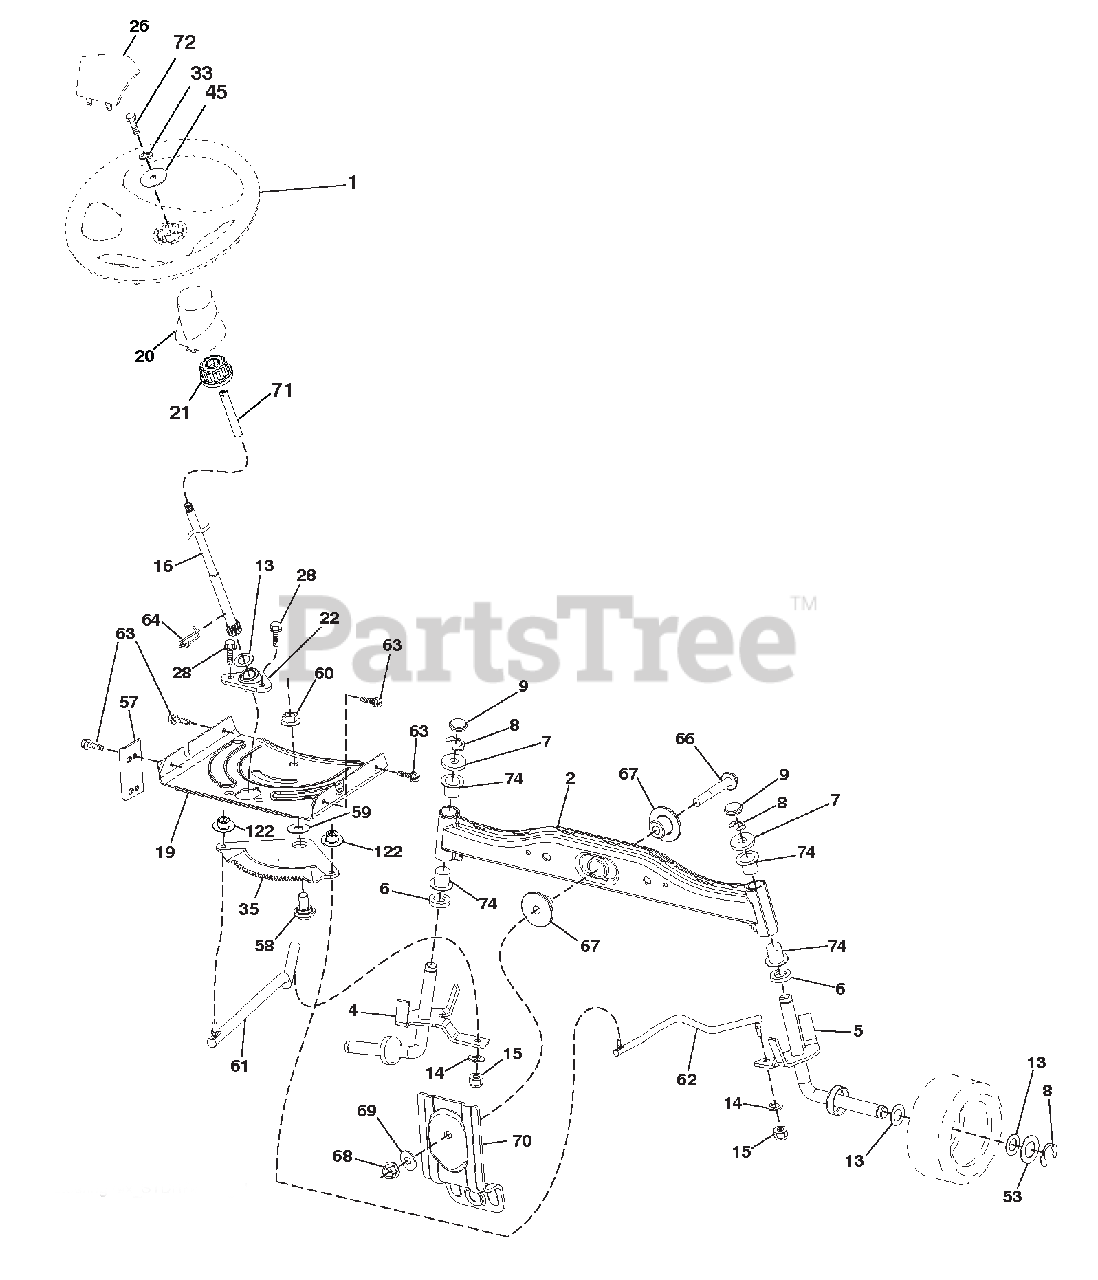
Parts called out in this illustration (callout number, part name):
1	Wheel Steering
2	AXLE ASM.WELDED
4	SPINDLE.ASM.LH
5	SPINDLE.ASM.RH
6	WAHSER THRUST .75 X 1.230
7	WASHER.25/32 X 1-5/8 X 16GA.
8	RING.KLIP.#T5304-75
9	CAP.SPINDLE.FR.TOP.BLK.
13	WASHER.25/32 X 1 1/4 X 16 GA.
14	Washer, Lock 3/8
15	NUT.CROWNLOCK.3/8-24
16	SHAFT.STEER.3/4 TEX.NON-PLATED
19	PLATE.STEER.DDL.NLT/NGT
20	BOOT STEERING
21	ADAPTER.WHEEL.STRG..760
22	STEERING SUPT.LOWER
26	Cap Wheel Steer
28	SCREW.HEXWSH THDR3/8-16X3/4.BL
33	Washer, Lock 5/16
35	GEAR SECTOR.PLATE.DDL.NLT/NGT
45	WASHER.11/32ID X2 3/8OD X 12GA
53	WASHER.HARDEN..793 X 1.637X060
57	BRACKET.UPSTOP.TEX
58	BOLT.SHOULDER.SECTOR.PIVOT.CFM
59	WASHER.THRUST.SECTOR.STEER.NLT
60	NUT.FLANGE LOCK.5/8-11
61	DRAGLINK.LH.BALLSTUD.DDL.
62	DRAGLINK.RH.BALLSTUD.DDL
63	SCREW.5/16-18X3/4.SMGML.TAP/BL
64	RETAINER.CLIP.SPRING.STEERING
66	BOLT.HEX.FGHD.7/16-14 X 3.SERR
67	BUSHING.PM.FRONT AXLE
68	NUT.LOCK.FLANGE.7/16-14.GR5
69	WASHER.1.5 X .505 X .118
70	BRACKET.DECK
71	Extension Steering
72	Bolt 5/16-18 x 14 w/Patch
74	BEARING COL STRNG BLK
122	CAP GEAR SECTOR
